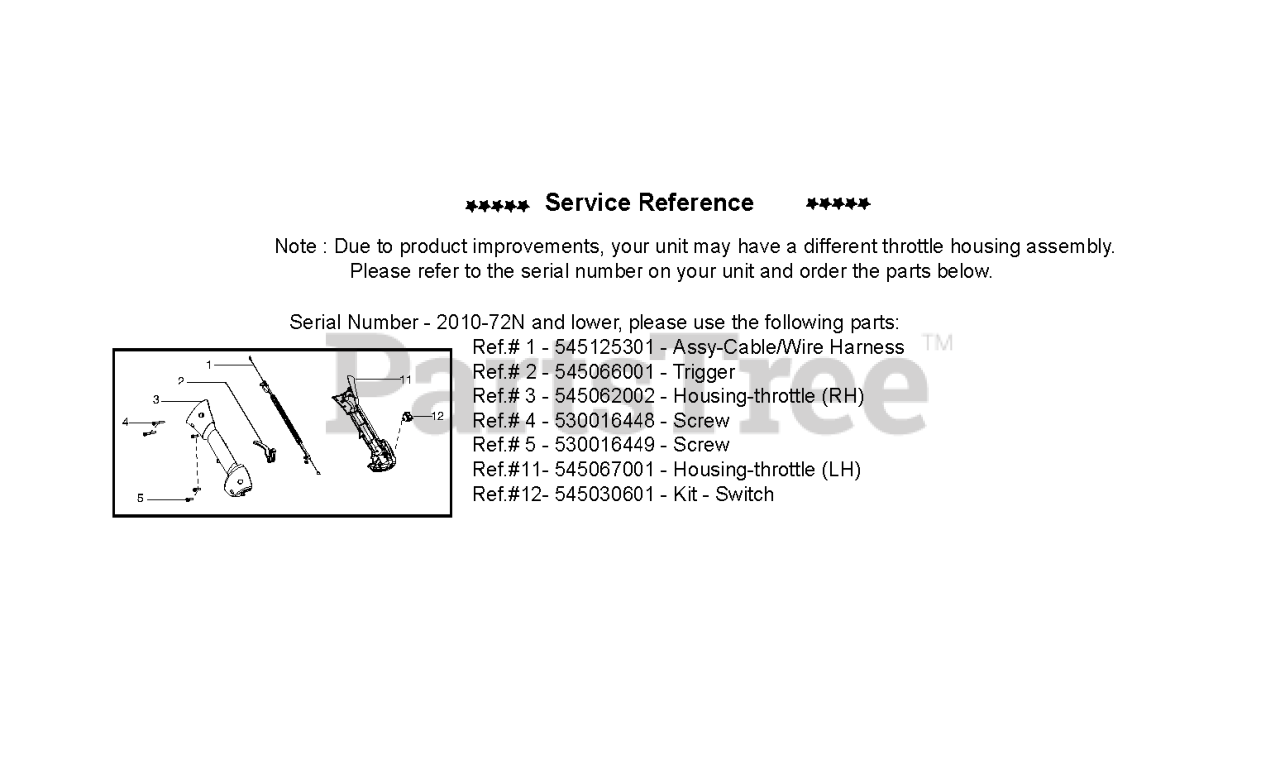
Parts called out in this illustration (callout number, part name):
1	ASSY-CABLE WIRE HARNESS
2	TRIGGER THROTTLE
3	HOUSING-THROTTLE (RH)
5	SCREW M4 X 1.75 PT 16MM
11	HSG THROTTLE LH
12	KIT SWITCH
